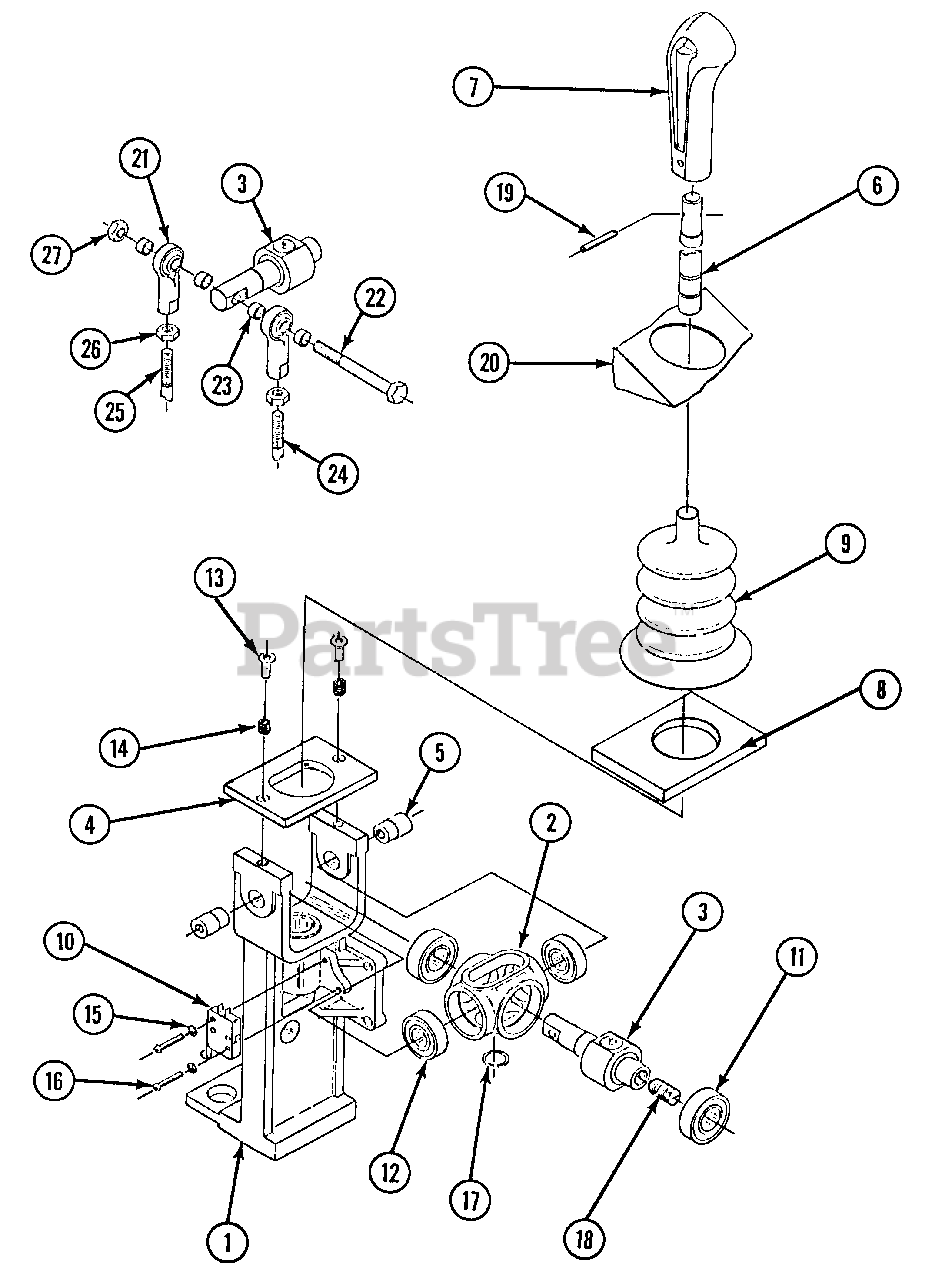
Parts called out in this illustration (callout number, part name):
1	JOYSTICK YOKE
2	PIVOT BLOCK
3	JOYSTICK PIVOT SHAFT
4	JOYSTICK TOP PLATE
5	TRUNION PIN
6	JOYSTICK HANDLE
7	HANDLE GRIP
9	BELLOWS, BOOT
10	SWITCH
11	BEARING
12	BEARING
13	FLAT HEAD SCREW 1/4-20 X 1/2
14	SETSCREW 1/4-20 X 5/16
15	#4 LOCKWASHER, INTERNAL STAR
16	#4-40 X 3/4 HEX-SLOTTED HEAD
17	SNAP RING
18	BALL PLUNGER, 3/8-16 X 5/8
19	ROLL PIN, 3/16 X 1
20	JOYSTICK COVER WLDT.
21	BALL JOINT, FEMALE 1/4-28
22	CAPSCREW, HEX HEAD, 1/4-20 X 2-1/4 GR.5
23	BUSHING
24	PUSH-PULL CABLE (RIGHT)
25	PUSH-PULL CABLE (LEFT)
26	NUT, 1/4-28
27	NUT, 1/4-20, STOVER
